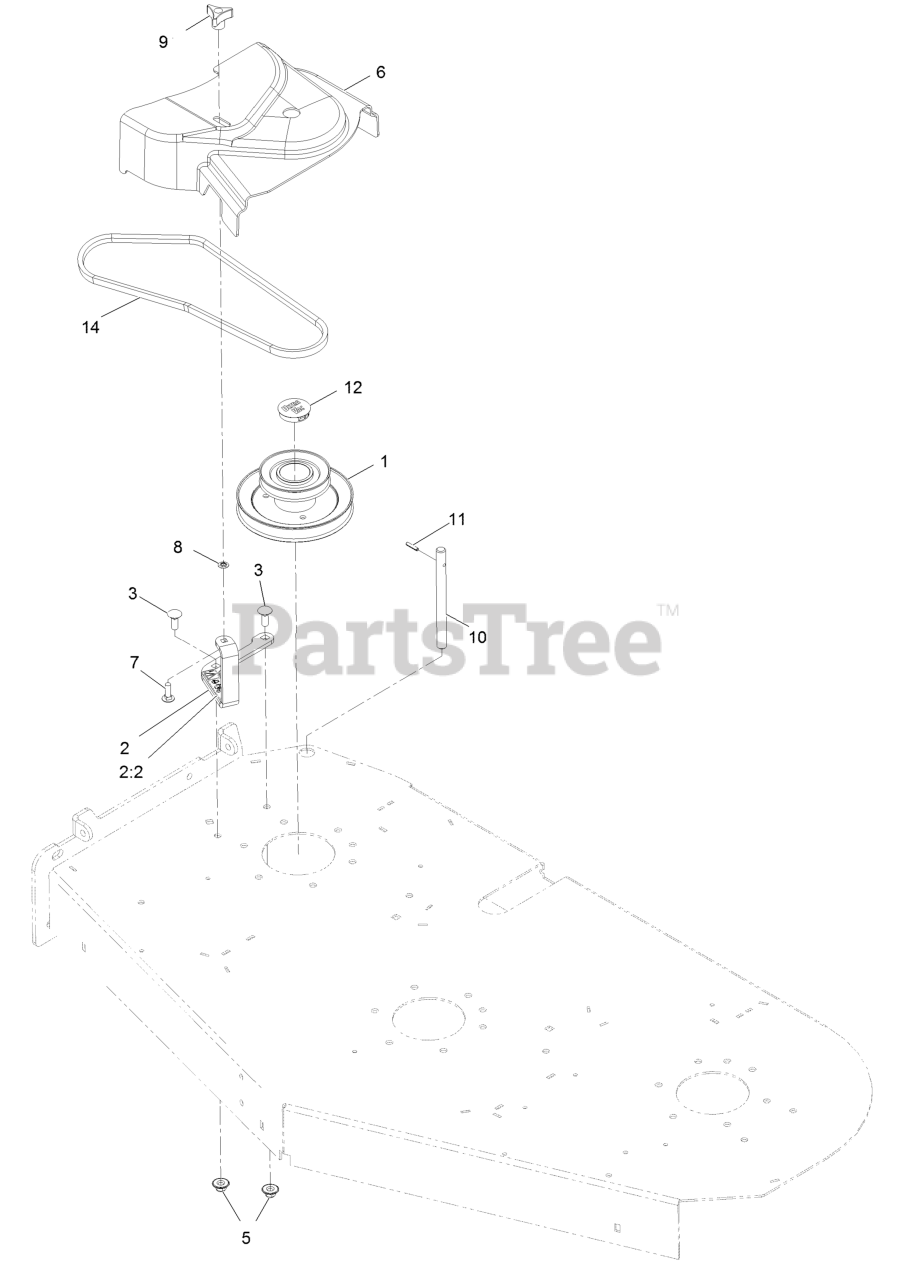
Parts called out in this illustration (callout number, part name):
1	JACKSHAFT-UV DRIVE 523
2	ASM-CVR BRKT W/DECAL
2:2	DECAL-DANGER
3	BOLT-CARR
5	Nut-Nyloc 3/8-16 Flg
6	COVER-BELT, UV 52
7	BOLT-CARR
8	RING-RETAINING, BOLT
9	KNOB-3 PRONG
10	SHAFT-CATCHER, GRASS
11	PIN-ROLL
12	PLUG, BLACK NYLON 1.75
14	BELT, BLOWER 52"DECK
